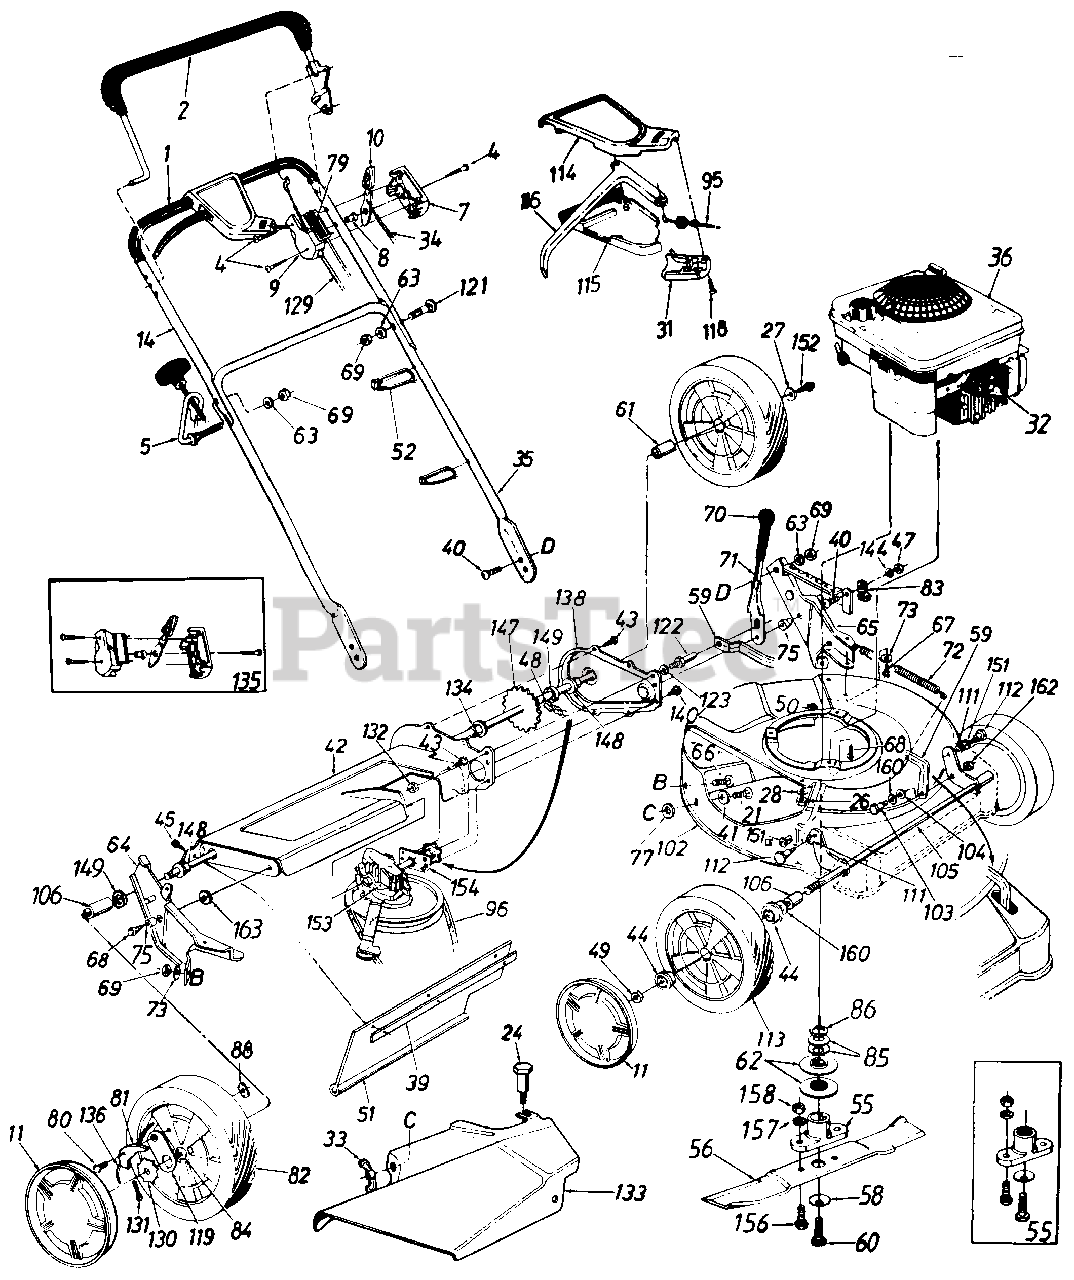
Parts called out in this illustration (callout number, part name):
1	Foam Grip
2	Control Handle Ass'y.-L.H.
4	Truss Mach. Scr. #12 x 1.5"
5	Rope Guide Bolt
7	Control Panel Half
8	Control Disc Pin
9	Clutch Panel Half
10	Throttle Control Lever
11	Hub Cap
14	Upper Handle-Painted
21	Carriage Bolt 1/4-20 x .62"
24	Shoulder Bolt .312 Dia. x 18 Lg.-Special
26	Hex Nut 1/4-20 Thd.
27	Bell-Wash. 1/4 0 I.D.
28	L-Wash. 1/4" I.D.'
31	S.P. Control Cover
32	Spark Plug Insulator
33	Wing Nut w/Washer
34	Throttle Control Wire 61"
35	Lower Handle-Painted
36	Engine
39	Retaining Strip
40	Truss Mach. Scr. 5/16-18 x .75"
41	Fl-Wash. .344" I.D. x .62"
44	Flange Ball Bearing 1/2" I.D.
45	Hex AB-Tap Scr. 1/4 X .62"
47	Hex Patch L-Nut 3/8-24 Thd.
48	#48 Chain .5" Pitch x 30 Links
49	Hex L-Nut 1/5 20 Thd.
52	Cable Tie
55	Blade Adapter Kit
56	21" Blade
58	Bell-Wash. .46" I.D. x 1.13"
59	Height Adj. Connecting Arm
60	Hex Bolt 7/16-20 x 1.5" Lg. (Grade 5)
61	Spacer .513" I.D. x .703" O.D. x .69" Lg.
62	Serrated Pulley Half
63	L-Wash. 5/16" I.D.
64	R.H. Handle Wheel Brkt. Ass'y.
65	L.H. Handle Wheel Brkt. Ass'y.
66	Carriage Bolt 5/16-18 x .62"
67	Hex B-Tap Scr. 5/16-18
68	Hex TT-Tap Scr. 3/8-16
69	Hex Nut 5/16-18 Thd.
71	Height Adj. Lever
72	Extension Spring 8" Lg.
73	Bell-Wash. 5/16" I.D.
75	Shld. Spacer .500" Dia.
77	Bolt Retainer 1/4 x .50" O.D.
79	Control Label
80	Shld. Scr. .342" Dia. x .268
81	Pawl
82	Wheel Ass'y. Comp.
84	Bearing 1/2" I.D.
85	Bell Washer 1.01" I.D.
86	Crankshaft Spacer
88	Flat Weld Nut 1/4-20 Thd.
95	S.P. Cable 48" Lg.
96	"V"-Belt
102	21" Deck Ass'y.
103	Shld. Bolt .5'/ Dia. x .295
104	Bell-Wash. .515" I.D. x 1.0"
105	Front Axle Ass'y.
106	Sleeve .526" I.D. x .690" O.D. x .880" Lg.
111	Intern. L-Wash. 3/8 I.D.
112	Shld. Bolt .575" Dia. x .42
113	Wheel Ass'y. Comp.
114	Self-Propelled Control Cover
115	Self-Propelled Control Cover
116	Control Lever
118	Fl-"C"-Sunk Hd. Tap Scr. #10 x .75" Lg.
119	Pawl Plate
121	Curved Carr. Bolt 5/16-18 x 1.38" Lg.
122	Shld. Pin 3/8-24 x 1.43" Lg.
123	L-Wash. 3/8" I.D.
129	Conrol Cable 46 Lg.
130	Ratche Wheel 1.62" O.D.
131	Cotter Pin 1/8" Dia. x 1.00" Lg.
132	Hex Jam Nut 3/8-24 Thd.
133	Side Chute Deflector Ass'y.
134	Hex Flange Bearing
135	Kit-Control Housing Comp.
136	Spring-Nylon
144	Fl-Wash. .385" I.D. x .87"
147	Rear Shaft Ass'y. 21.94" Lg.
148	Hex Flange Bearing .506" I.D. Plastic
149	Fl-Wash. .531" I.D. x .930"
151	Flanged Nyliner Brg.
152	Hex Bolt 1/4-20 x .62" Lg. (Grade 5)
153	Transmission Comp.
156	Hex Bolt 3/8-24 x 1.0" Lg.
157	L-Wash. 3/8" I.D. '
158	Hex Nut 3/8-24 Thd.
160	Fl-Wash. .51" I.D. x .75" O.D.
162	Hex Jam Nut 3/8-16 Thd.
163	Fl-Wash. .383 I.D.
17055B-0498	AXLE ASSY-CHAIN - OLD CUB YELLOW (0498)
17055B-0637	AXLE ASSY-CHAIN - POWDER BLACK (0637)
17055B-0638	AXLE ASSY-CHAIN - MTD/TROY-BILT RED (0638)
17055B-0650	AXLE ASSY-CHAIN - RED METALLIC (0650)
17055B-0665	AXLE ASSY-CHAIN - YARDMAN GREEN (0665)
17055B-0667	AXLE ASSY-CHAIN - MIDNIGHT BLUE (0667)
17055B-0691	AXLE ASSY-CHAIN - BLACK JACK (0691)
